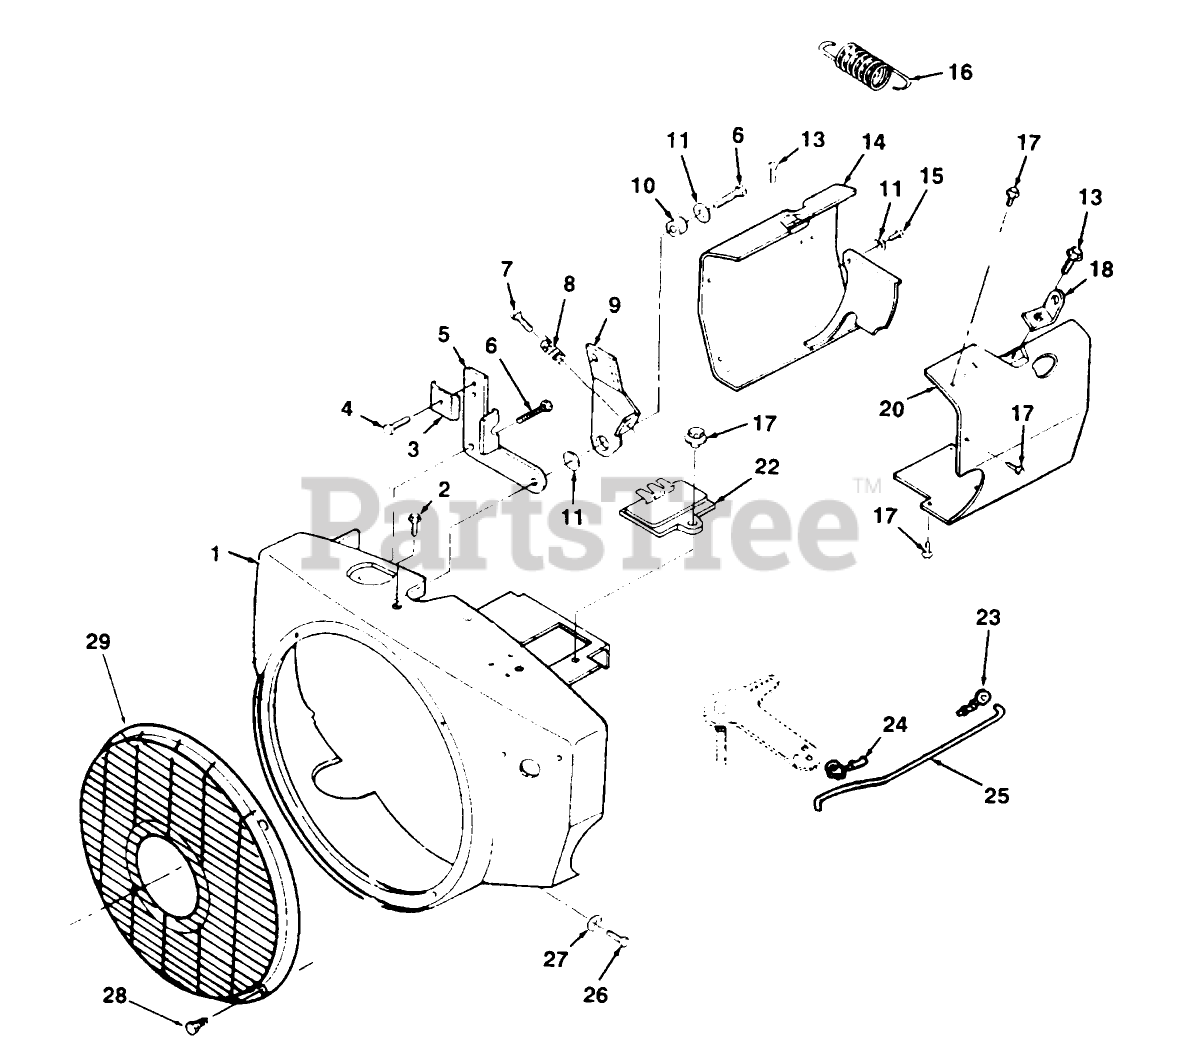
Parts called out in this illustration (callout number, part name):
1	HOUSING-BLOWER
2	SCREW-HWH
4	SCREW-TAPPING
5	BRACKET-GOVERNOR
6	SCREW-HWH
7	Screw-Hex. Hd.
8	SPRING
10	BUSHING
11	WASHER-FLAT
13	SCREW-HWH
14	HOUSING-AIR CYLINDER, LH
15	SCREW-HH
16	SPRING
17	SCREW-HWH
18	BRACKET-LIFTING
20	HOUSING-AIR CYLINDER, RH
22	REGULATOR
25	ROD-GOV CONTROL
26	Screw-Tapping
27	WASHER-FLAT
28	SCREW-PAN HEAD
29	GUARD-STATIONARY
